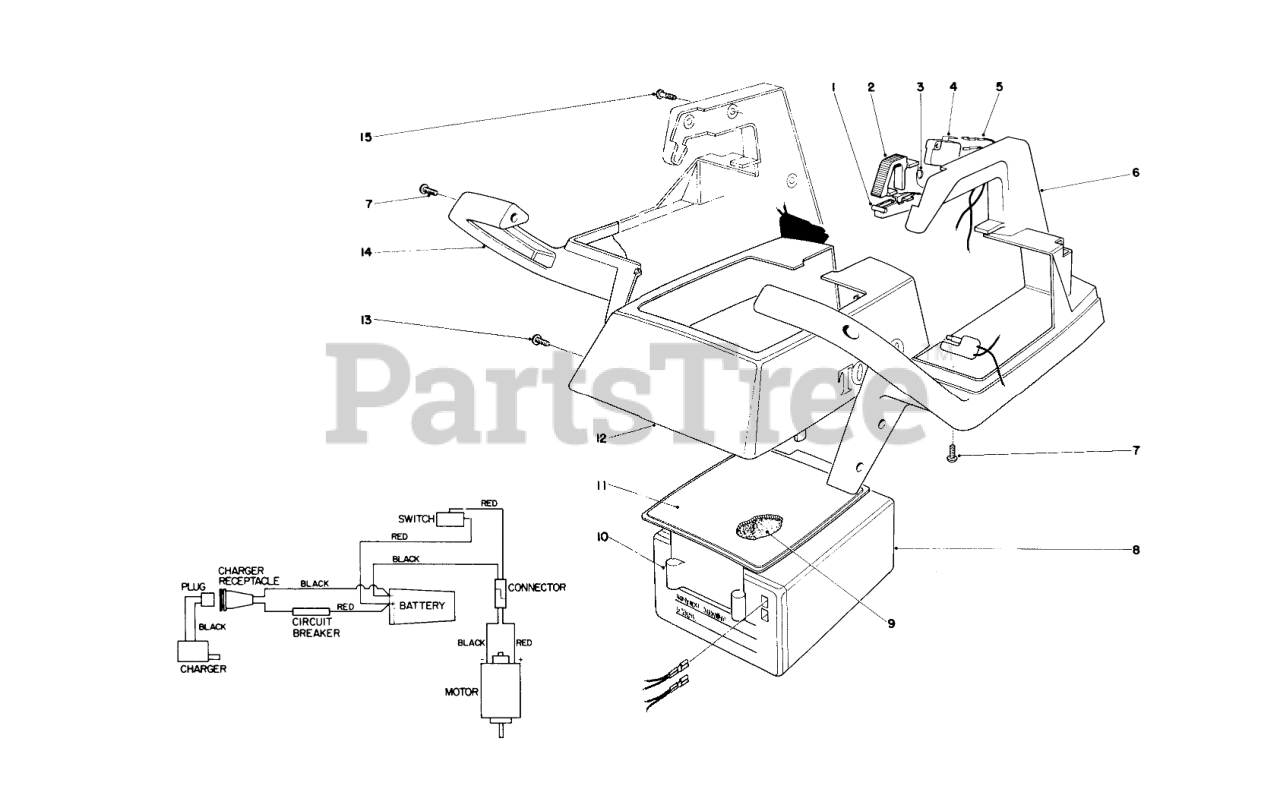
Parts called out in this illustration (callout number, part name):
1	TRIGGER
2	TRIGGER LOCK
3	SPRING
4	Switch
5	Wiring Harness
6	Left Hand Case
7	Screw
8	BATTERY
9	FOAM PAD
10	CONTROL PANEL, CL-710
11	Decal, Control Panel
12	Cover
13	10-16 X .31 SCREW
14	Right Hand Case
15	SCREW-PPH
